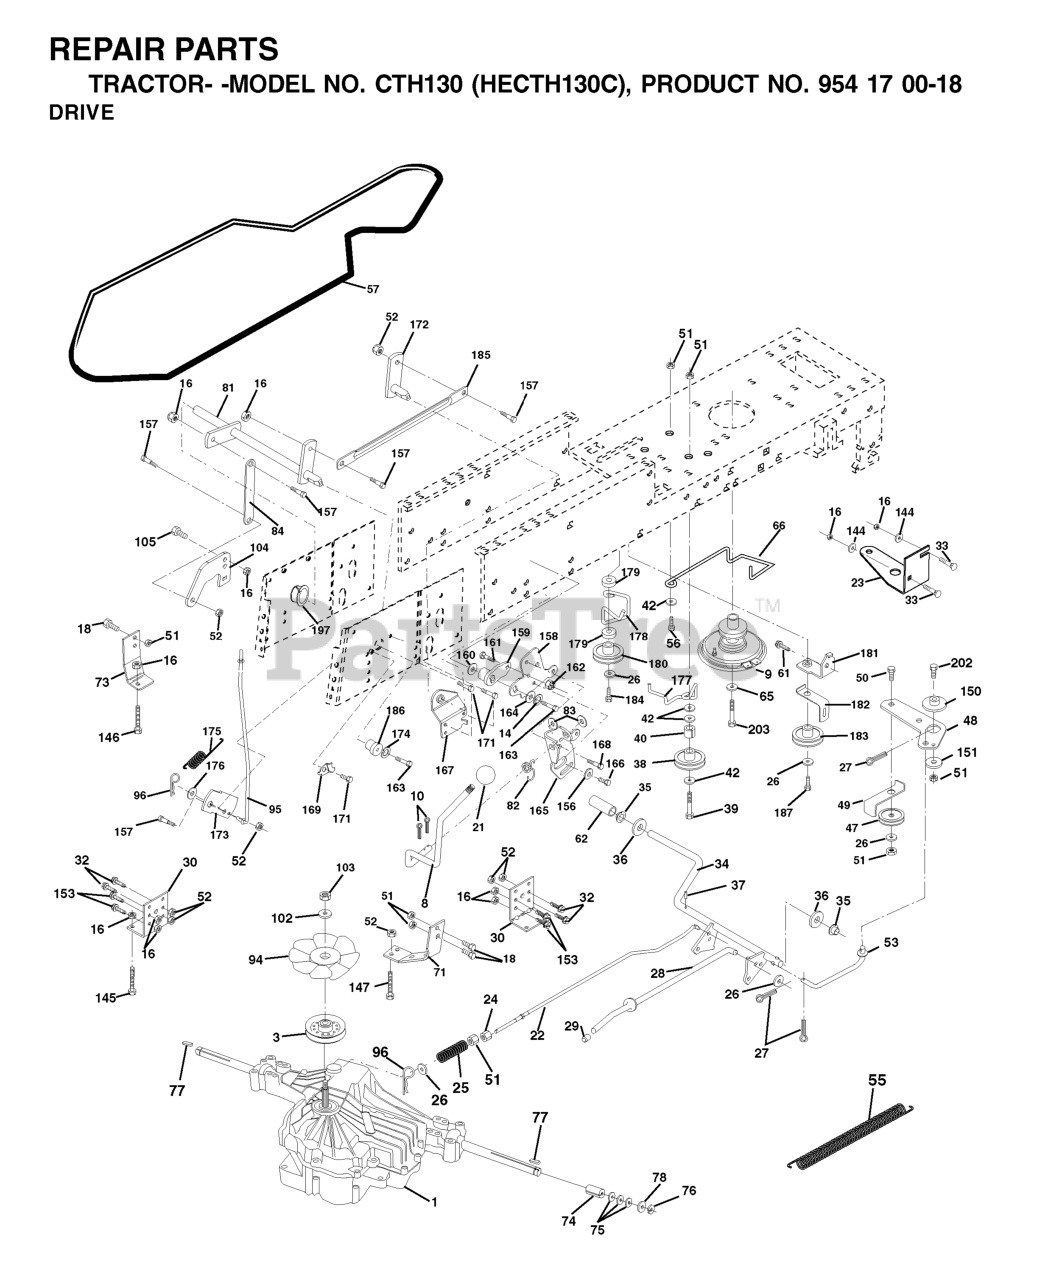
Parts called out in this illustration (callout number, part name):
3	PULLEY, TRANSAXLE
8	ROD.SHIFT.FENDER.ADJ.LT.CRD
9	CLUTCH ASSY
10	PIN COTTER
14	LOCKWASHER
16	NUT.71038.31-18.HEX.NYLOCK
21	KNOB.DUCKHEAD.1/2
23	Bracket Clutch Noram
24	NUT
25	SPRING ROD LT
26	WASHER
27	COTTER PIN
28	ROD BRAKE PARK LT
29	PLUNGER CAP
30	BRKT, TRNSXLE MNT 20"
32	BOLT
33	RP BOLT 5/16-18 X3/4 ZN/YEL GR
35	BEARING.NYLON
37	DRIVE PIN
38	PULLEY.FLAT
42	WASHER
47	IDLER PULLEY
48	BELLCRANK, CLUTCH
49	RETAIN BELT
50	BOLT
52	LOCKNUT
53	LINK, CLUTCH LT
55	SPRING, RETURN LT
57	V-BELT.0650.CRD.TRACTOR
61	SCREW 3/8-16X3/4
62	COVER, PEDAL (1 2)
65	LOCKWASHER
66	KEEPER BELT ENGINE
71	STRAP LH TORQUE
73	STRAP TORQUE RH HYDRO
74	SPACER SPLIT
77	SQUARE KEY
82	SPRING,TORSION
83	WASHER
84	LINK TRANSAXLE
94	FAN 7" HYDRO
95	BYPASS CONTROL ASM
96	RETAINER M
103	NUT.HEX.1/2-20
104	CONTROL ARM
144	Washer 11/32 x 5/8 x 16 Ga SD
146	Bolt Hex Flanged 5/16-18 Unc x 2
147	Bolt Hex Flanged 5/16-18 Unc x 2
150	BUSHING.BELLCRANK.GRD.DR
151	WASHER 12/32X2X10GA
153	BOLT RB
156	WASHER.SRRTD.5/16
157	BOLT SHOULDER 5/16-18
158	BRACKET
159	HUB
160	Washer 29/32 x 1 - 1/4 x 16 Ga.
161	BOLT
162	NUT.CROWNLOCK.1/4
164	Washer 5/8 x .281 x 10 Ga.
165	RP BRACKET
167	BRACKET.SUPT.SHIFT.CRD
168	BOLT.SHOULDER.5/16-18X
169	PLATE.FASTENING.CROSS.SHAFT
174	LOCKWASHER
175	SPRING.BYPASS.CRD
176	Washer 7/32 x 1/2 x 16 Gauge
180	PULLEY.FLAT.IDLER
181	BRKT.IDLER.GRD.DR.CRD
182	KEEPER BELT
183	PULLEY.V-IDLER
184	SCREW.HXWSH.3/8
186	HUB.TAPERED.ROUND.CRD
187	SCREW
197	NYLINER SNAP 5/8" ID
202	BOLT.3/8-16X1.50
203	BOLT.HEX.7/16-20 X 5
